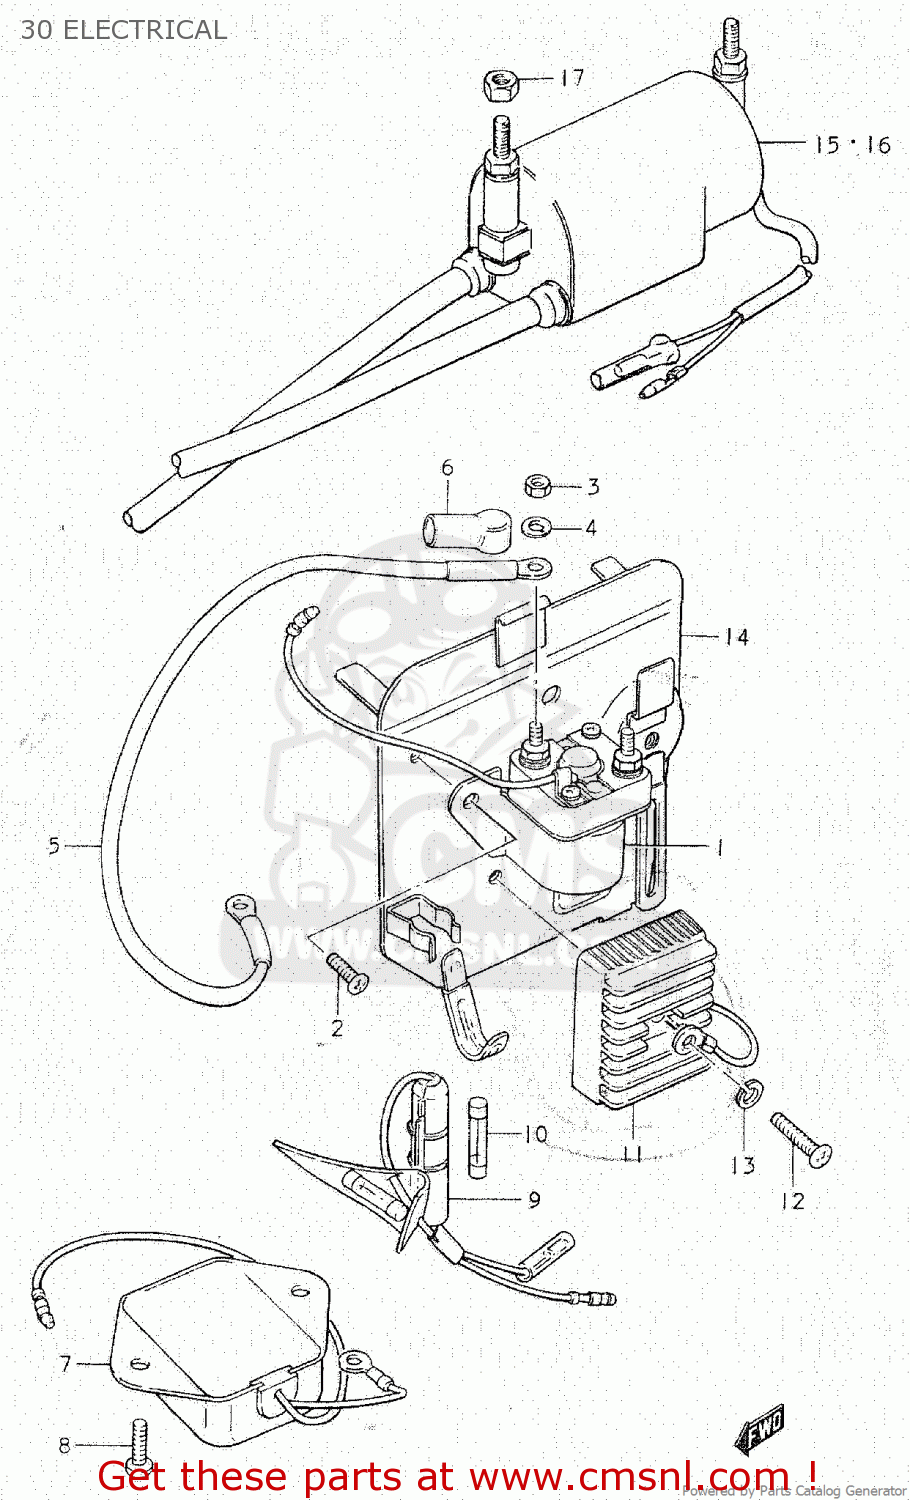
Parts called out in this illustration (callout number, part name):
1	RELAY ASSY,STARTING MOTOR
2	SCREW
3	NUT 6MM
4	LOCK WASHER
5	WIRE,STARTER MOTOR LEAD
6	CAP,STARTER RELAY
7	REGULATOR ASSEMBLY
8	SCREW
9	BOX ASSEMBLY,FUSE
10	FUSE(15A)
11	RECTIFIER ASSY
12	SCREW
13	LOCK WASHER
14	HOLDER COMP,ELECTRONIC PARTS
15	COIL ASSEMBLY,IGNITION
16	COIL ASSEMBLY,IGNITION
17	NUT
